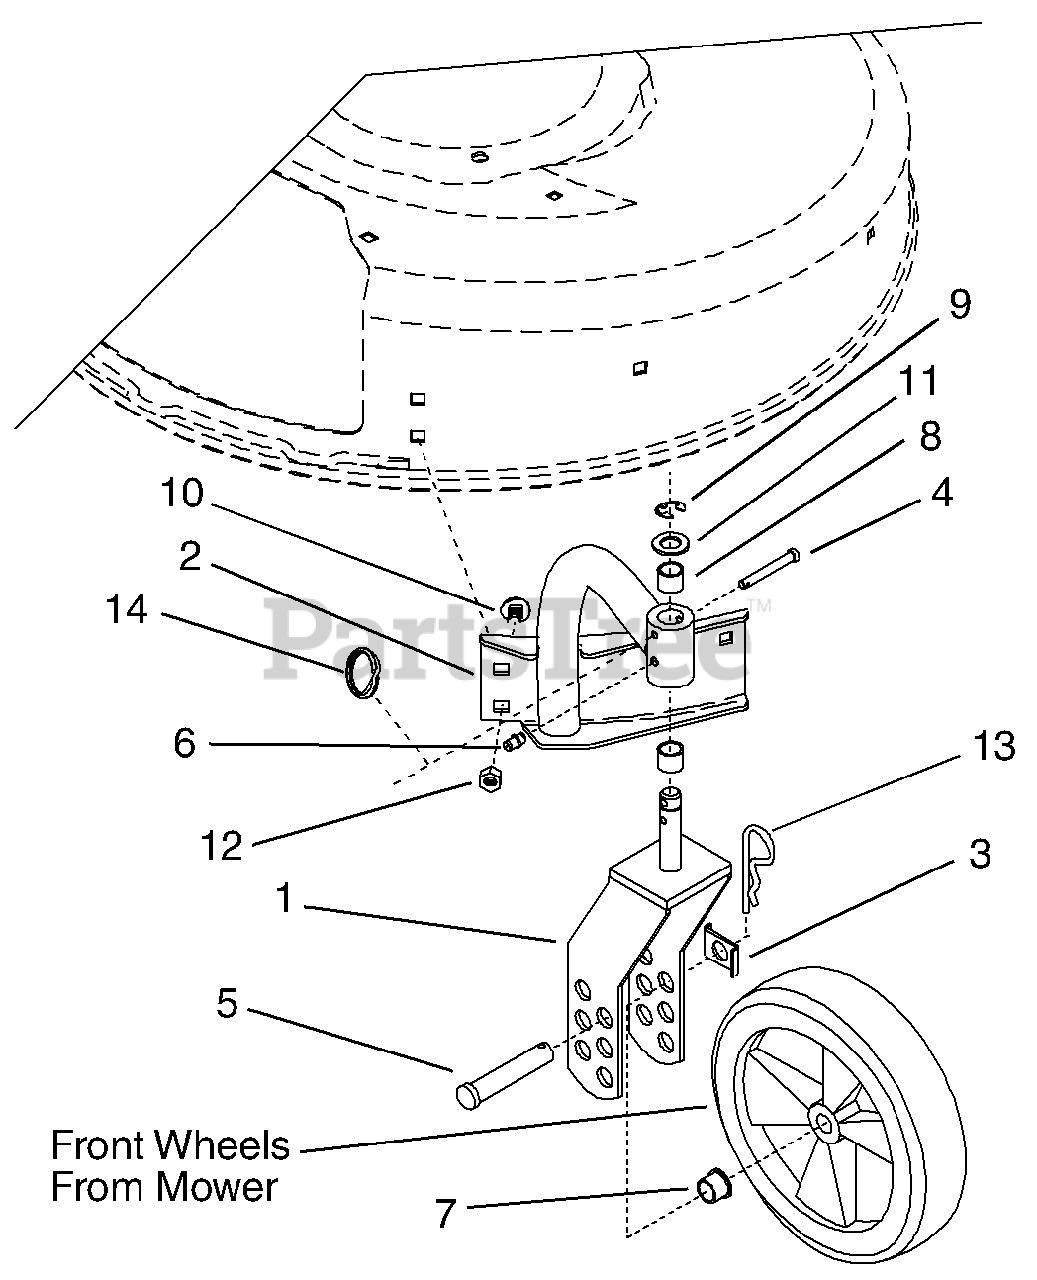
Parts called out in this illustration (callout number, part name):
1	Wheel Yoke Weldment
2	Left Mount Arm Weldment
2	Right Mount Arm Weldment
4	Pin-Clevis .25 x 1.75
5	Clevis Pin
6	Fitting-Lube .25-28 x .256
7	Bushing-Flange .500 x .625 x .500 x .750
8	Bushing-Sleeve .625 x .750 x .500
9	Ring-Retaining-External .625 x .042
10	Bolt-Round Head Square Neck .31-18
11	Washer-Flat-Steel .630 x 1.005 x .062
12	Nut-Locking Center .31-18
13	Pin-Hair Ext. .12 x .31 x 2.37
14	Kickout Ring
